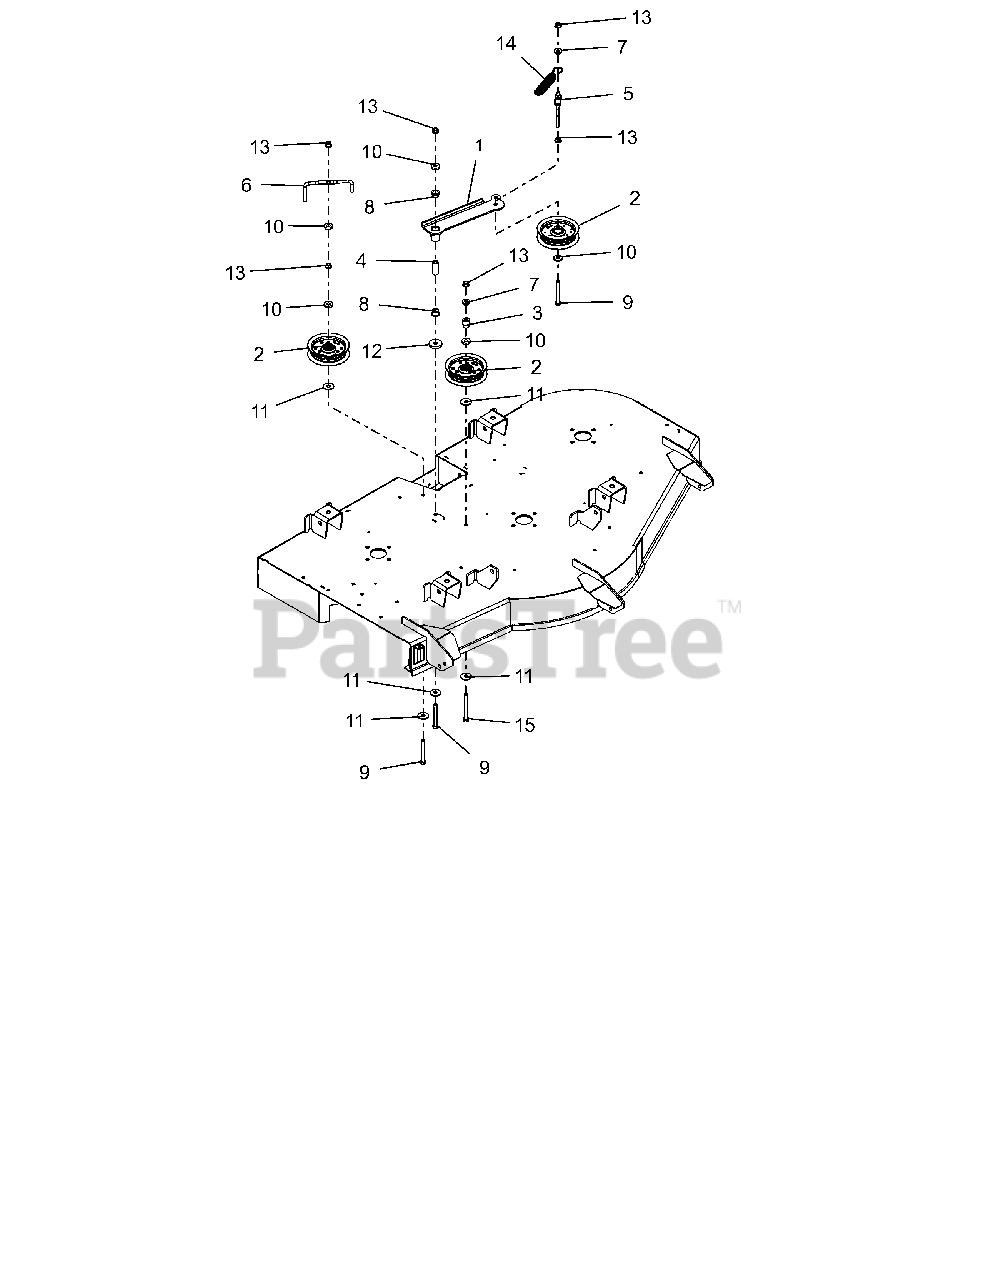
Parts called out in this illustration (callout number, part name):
1	WLDMT, IDLER ARM-52"
2	ASM, IDLER 4"
3	BUSHING, IDLER (P/M)
4	SPACER, .375IDX.625ODX1.66 PM
5	WIREFORM, BELT FINGER
6	WIREFORM, BELT FINGER
7	BSHG-FLG .385X.500X.875X.406
8	BSHG-FLG, .625X.750X.500X1.00
9	BLT, HEX .38-16X3.00F G5 ZCC
10	WSHR, FLT .406X1.00X.188 ZCC
11	WSHR FL STL .406X1.25X.10ZC120
12	WSHR, FLT .406X1.50X.245 ZCC
13	NUT-LK-TOP-FLG .38-16 ZC120
14	SG-TENS .135X.98X6.0 WLD 62
15	BLT, HEX .38-16X3.50 G5 ZCC
